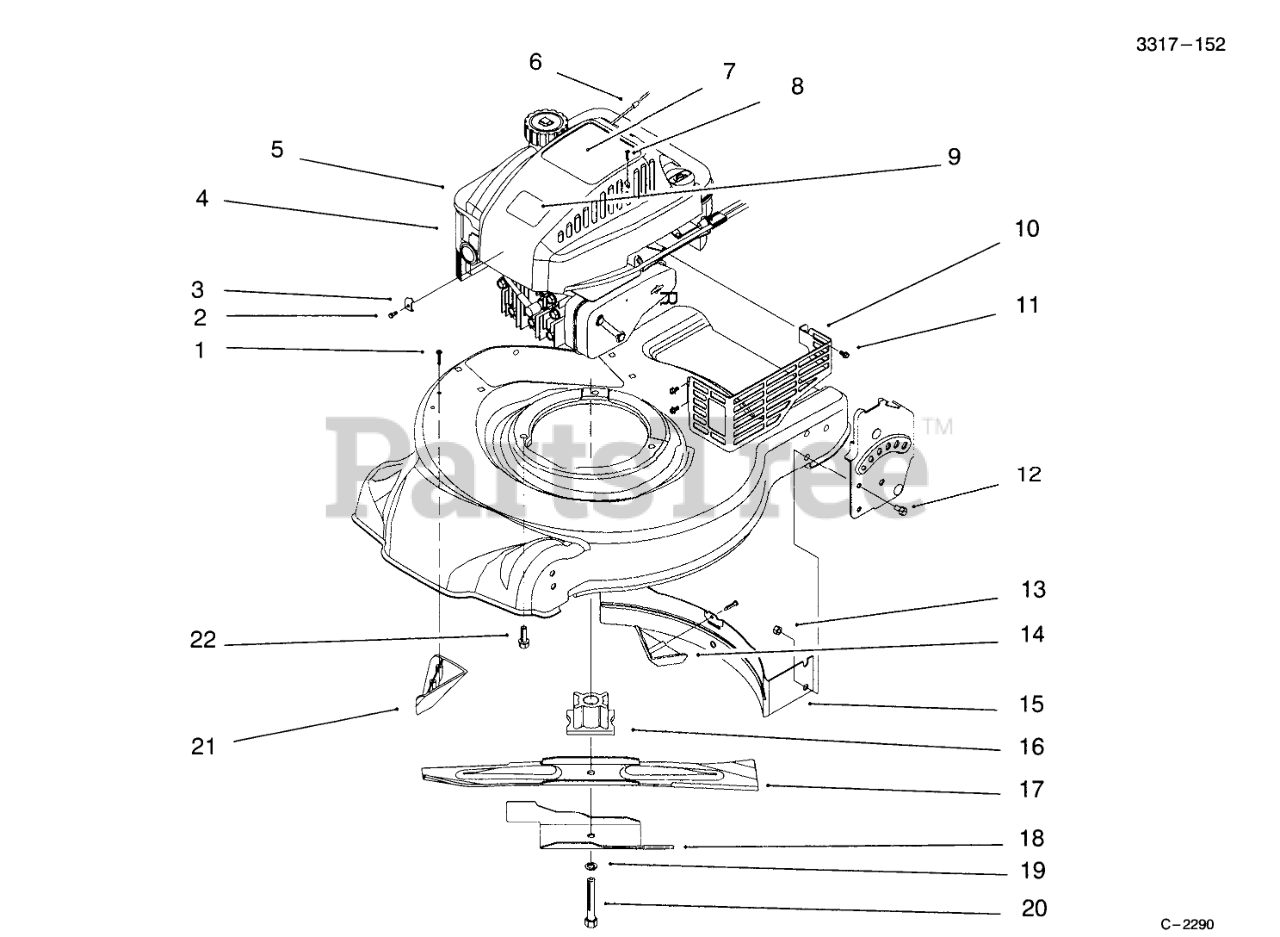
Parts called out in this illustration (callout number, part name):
1	SCREW-PPH
2	SCREW-CLAMP
3	CLAMP-CASING
4	Shroud-Qt Wedge (Model No. 20443 Only)
5	SHROUD-ENGINE
6	STOP-ROPE
7	OBS EXCEPT FOR SERVICE DECAL - ENGINE
8	SCREW-PPH
9	PLATE-LOGO
10	SHIELD-MUFFLER
11	SCREW-HWH
12	SCREW-HH
13	NUT-LOCK, NI
14	KICKER-REAR
15	Baffle-Rear
16	BLADE RETAINER
17	Blade
18	Accelerator
19	WASHER-LOCK
20	SCREW-BLADE
21	KICKER - SIDE
22	SCREW-HWH
